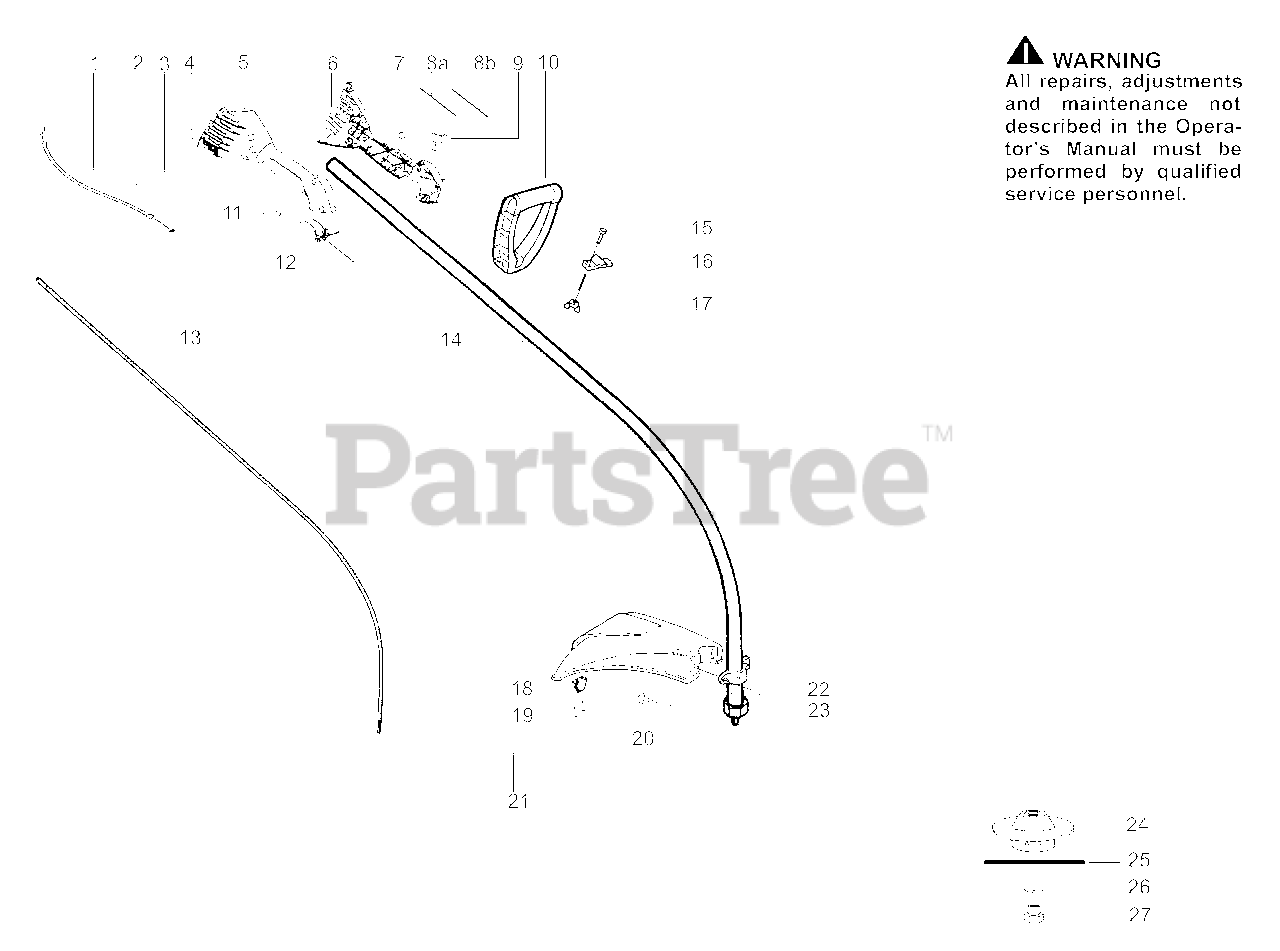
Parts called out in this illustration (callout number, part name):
1	Assy-Throttle cable
2	Screw-alignment
3	Screw-(10-24)
4	Screw-handle/fan hsg.
5	Throttle Hsg.-Right
6	Kit-Left Throttle Hsg.
7	Nut-Hex (10-24)
8A	Assy-Front wire
8B	Assy-Front wire (upper)
9	Kit-Switch
10	Handle-Assist
12	Trigger-Throttle
13	Shaft-Flex
14	Assy-Driveshaft
16	Clamp-Handle assist
17	Wingnut
18	Limiter-Line
21	Kit -Shield Ass'y.
22	Wingnut
24	Assy-Cutting Head
25	Tube-Line
27	Nut-Shoulder
